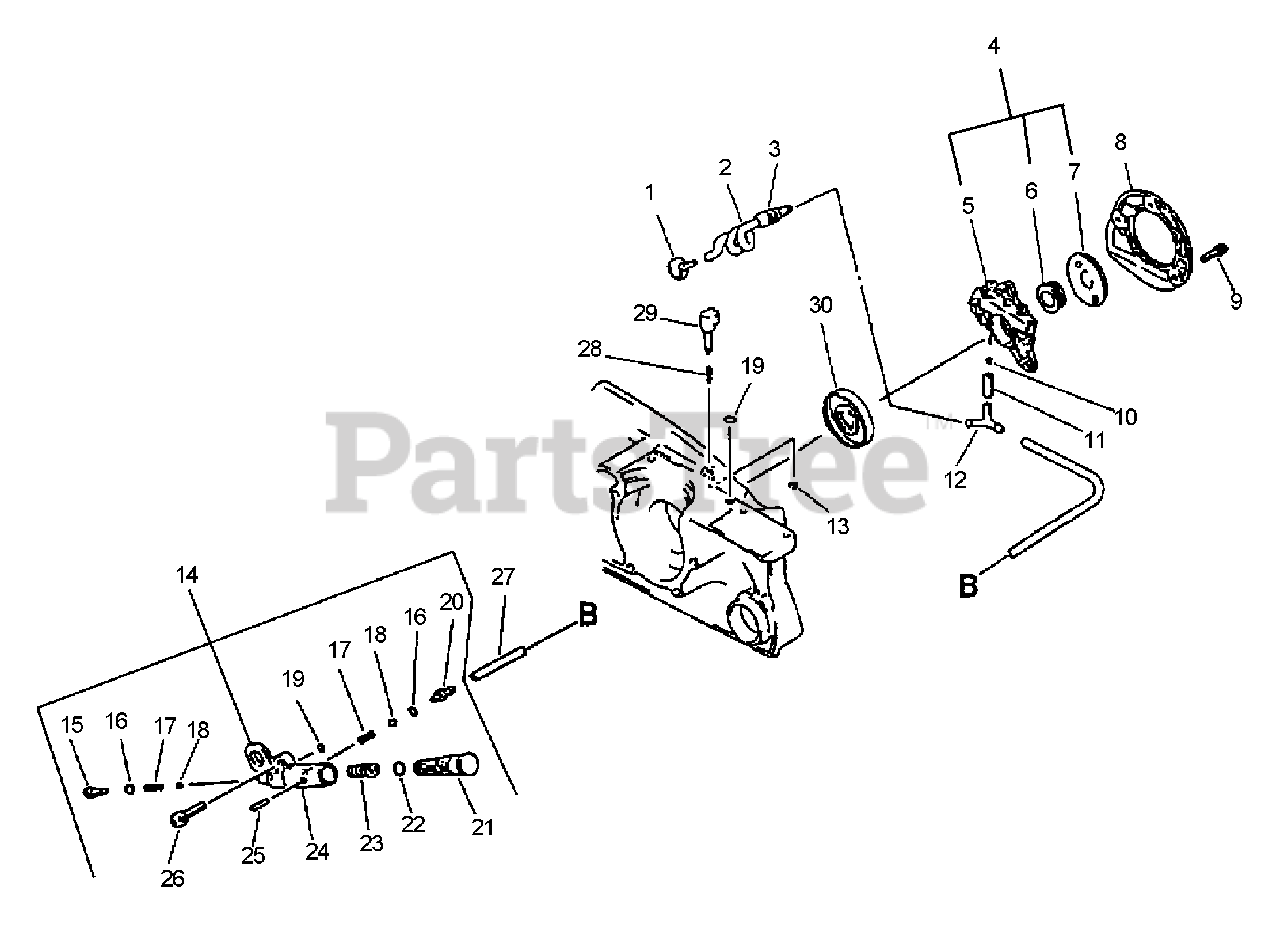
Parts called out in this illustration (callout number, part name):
1	FILTER, OIL
2	PIPE - OIL
4	AUTO-OILER ASSY
5	AUTO-OILER ASSY
6	GEAR - WORM
8	COVER, OIL PUMP
9	SCREW - 4X14
10	CLIP - 6.5
11	PIPE - 3X6X20 -- BLACK
12	CONNECTOR, PIPE
13	RING, RETAINING - 3
14	OIL PUMP ASSY
15	ADAPTER, OIL PUMP
17	SPRING, VALVE
18	VALVE, BALL
19	O-RING - 3
21	PISTON, OIL PUMP
22	O-RING - 7
24	BODY, OIL PUMP
25	PIN - SPRING -- 2X16
26	SCREW - 5X14
27	PIPE - 3X6X210 -- BLACK
29	DIAL, AUTO-OILER
30	SEAL, OIL
